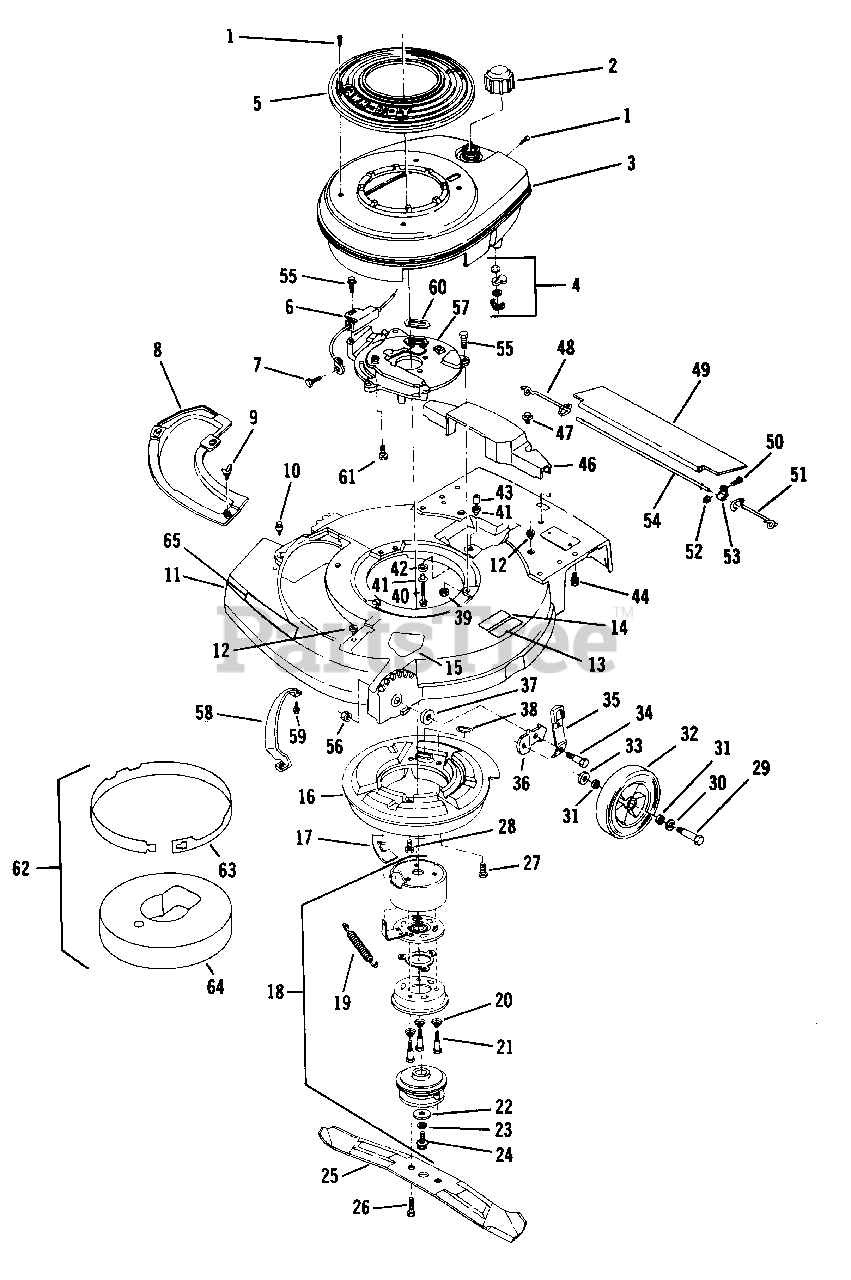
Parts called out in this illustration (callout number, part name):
1	Screw
2	Fuel Cap
3	Shroud-Engine
4	Fuel Shut-Off Assembly
5	Cover-Shroud
6	Control Cable Assembly
7	Bolt-Shoulder Clutch Arm
8	Cover Plate
9	Wing Screw
10	Screw-Plate and Chute Mounting
11	Housing Assembly
12	Grommet
13	Starting Pad
14	Decal-Starting Pad
15	Decal-Blade Contact Warning
16	Muffler Assembly
17	Shield-Actuator
18	Clutch Brake Assembly
19	Spring
20	Spring-Pressure
21	Screw-Shoulder
22	Washer
23	Lock Washer
24	Screw-Socket Head
25	Blade-21"
26	Screw-Sems-Blade
27	Screw-Muff. to Block
28	Screw-Muff. to Engine Mounting Plate
29	Bolt-Wheel-Front Washer
30	Washer
31	Washer-Felt
32	Wheel-Front
33	Washer
34	Shoulder Bolt
35	Knob and Spring Assembly
36	Bracket-Wheel Hght. Adj.
37	Washer
38	Seal-Exhaust
39	Nut-Eng. Mtg. Plt. to Hsg.
40	Screw
41	Spacer
42	Grommet
43	Spacer
44	Screw-Handle Bracket
46	Cover-Drive Axle
47	Screw-Axle Cover Mtg.
48	Spring-R.H.
49	Shield-Trailing
50	Screw
51	Spring-L.H.
52	Nut
53	Clamp
54	Rod-Trailing Shield
55	Screw-Eng. Mtg. Plt. and Cable Assembly to Housing
56	Nut
57	Plate-Eng. Mtg.
58	Toe Bar
59	Screw
60	Gasket Exhaust
61	Screw-Eng. Mtg. Plt. to Blk.
62	Muffler Seal and Shield Kit
63	Shield-Muffler Seal
64	Seal-Muffler
65	Decal-Clutch
